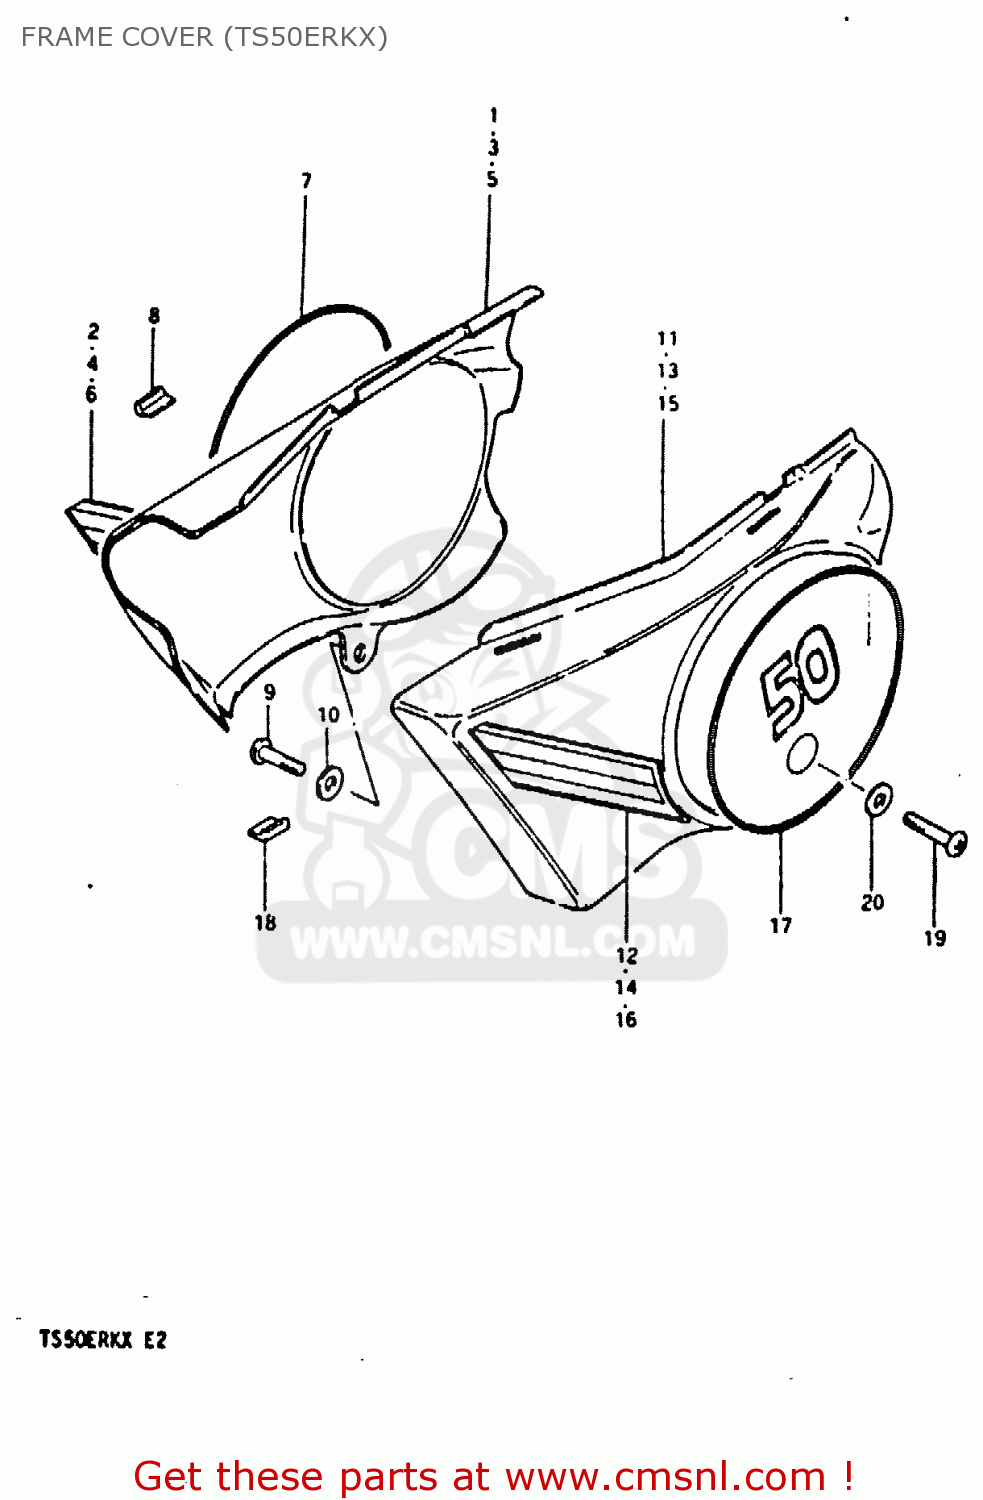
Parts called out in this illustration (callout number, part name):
1	COVER, FRAME RH (RED)
2	TAPE, STRIPING RH
3	COVER,FRAME RH
4	TAPE, STRIPING RH
5	COVER,FRAME RH
6	TAPE, STRIPING RH
7	EMBLEM, RH (WHITE)
8	CUSHION,FRAME COVER
9	SCREW
10	WASHER
11	COVER, FRAME LH (RED)
12	TAPE, STRIPING LH
13	COVER, FRAME LH (BLUE)
14	TAPE, STRIPING LH
15	COVER, FRAME LH (WHITE)
16	TAPE, STRIPING LH
17	EMBLEM, LH (WHITE)
18	CUSHION,FRAME COVER
19	SCREW
20	WASHER
